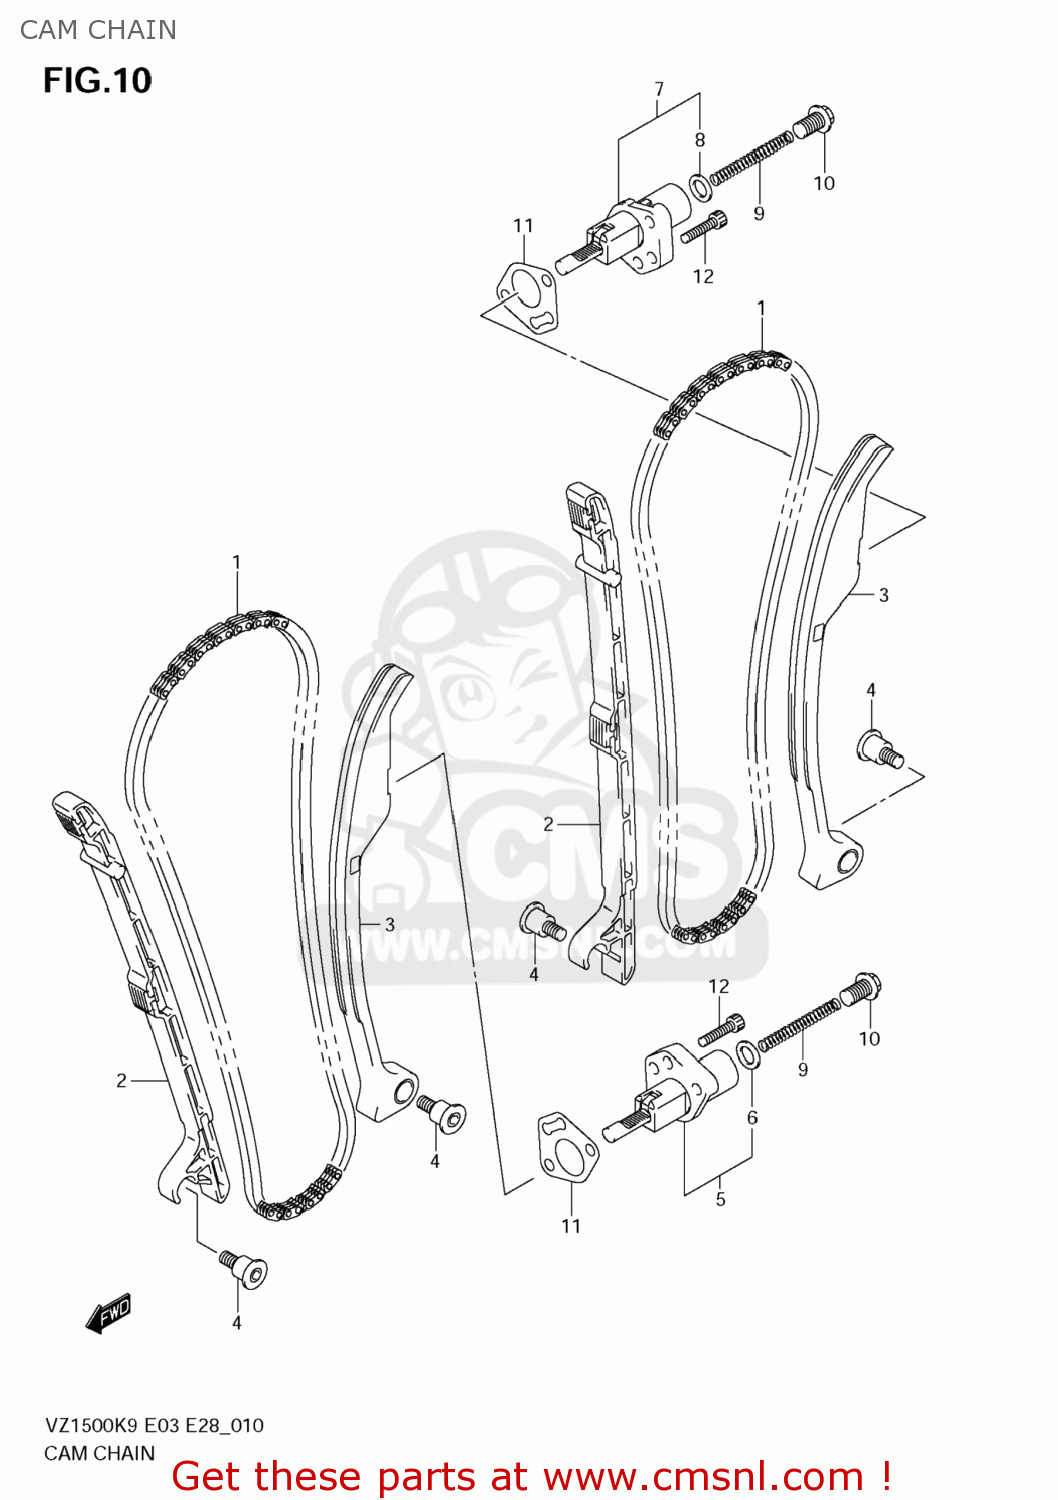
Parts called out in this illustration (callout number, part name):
1	CHAIN,CAMSHAFT DRIVE
2	GUIDE,CAM CHAIN
3	TENSIONER,CAM CHAIN
4	BOLT,CAM CHAIN TENSIONER
5	ADJUSTER ASSY,TENSIONER FR
6	GASKET,TENSIONER ADJUSTER (NAS)
7	ADJUSTER ASSY,TENSIONER RR
8	GASKET,TENSIONER ADJUSTER (NAS)
9	SPRING
10	PLUG,TENSIONER ADJUSTER
11	GASKET,TENSIONER ADJUSTER (NAS)
12	BOLT
